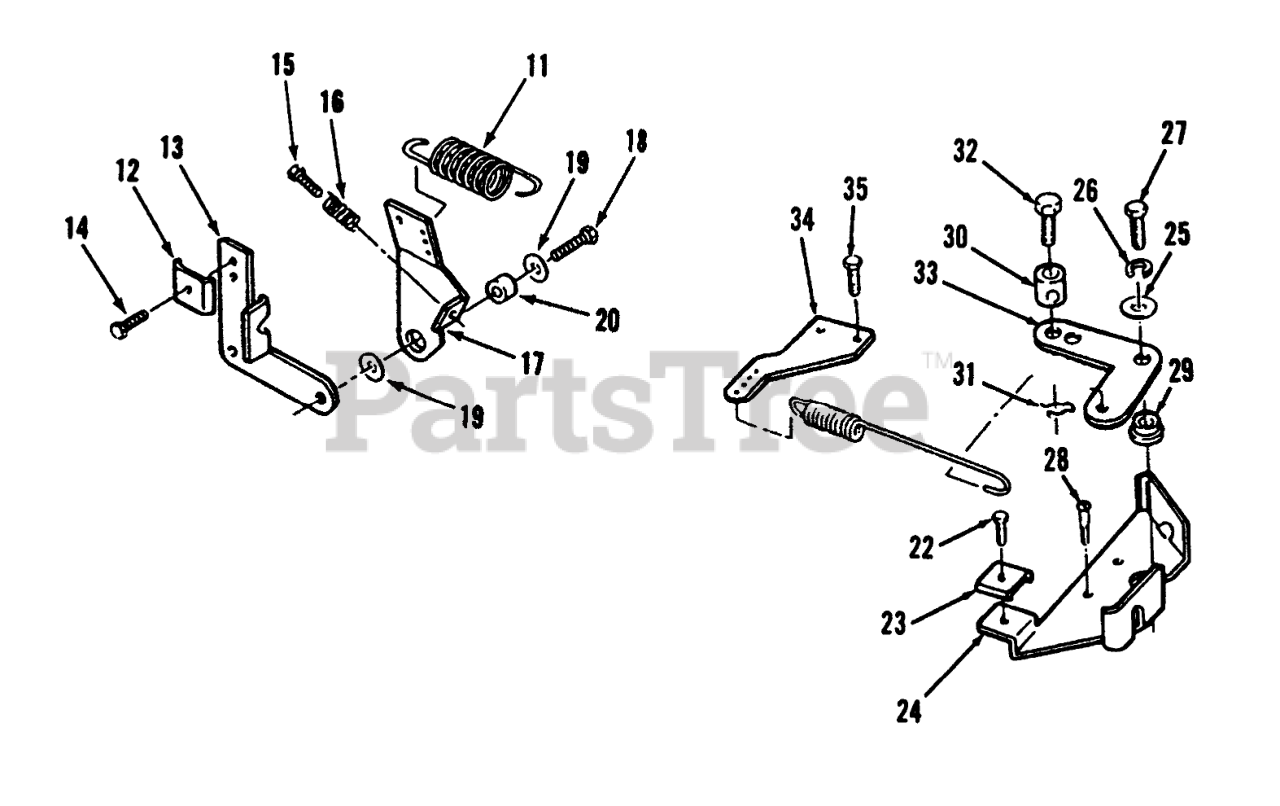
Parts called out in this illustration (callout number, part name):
11	Spring
13	BRACKET
14	Bolt
15	SCREW-TAP
16	Spring
17	GOVERNOR CONTROL ARM
18	SCREW-HWH
19	Screw
20	Bushing
22	TAPPING HEX HD CS
24	BRKT-GOVERNOR CONTRL
25	WASHER-FLAT
26	WASHER-LOCK, SPRING
27	SCREW - CAP HEX HEAD
28	HEX HD CAP SCREW
29	BUSHING-GOV CONTROL
30	Oil Seal
31	PIN-COTTER
32	Bolt
33	LINK-GOV CONTROL
34	ADAPTER-GOV ARM
35	SCREW-TAPPING PAN HD
